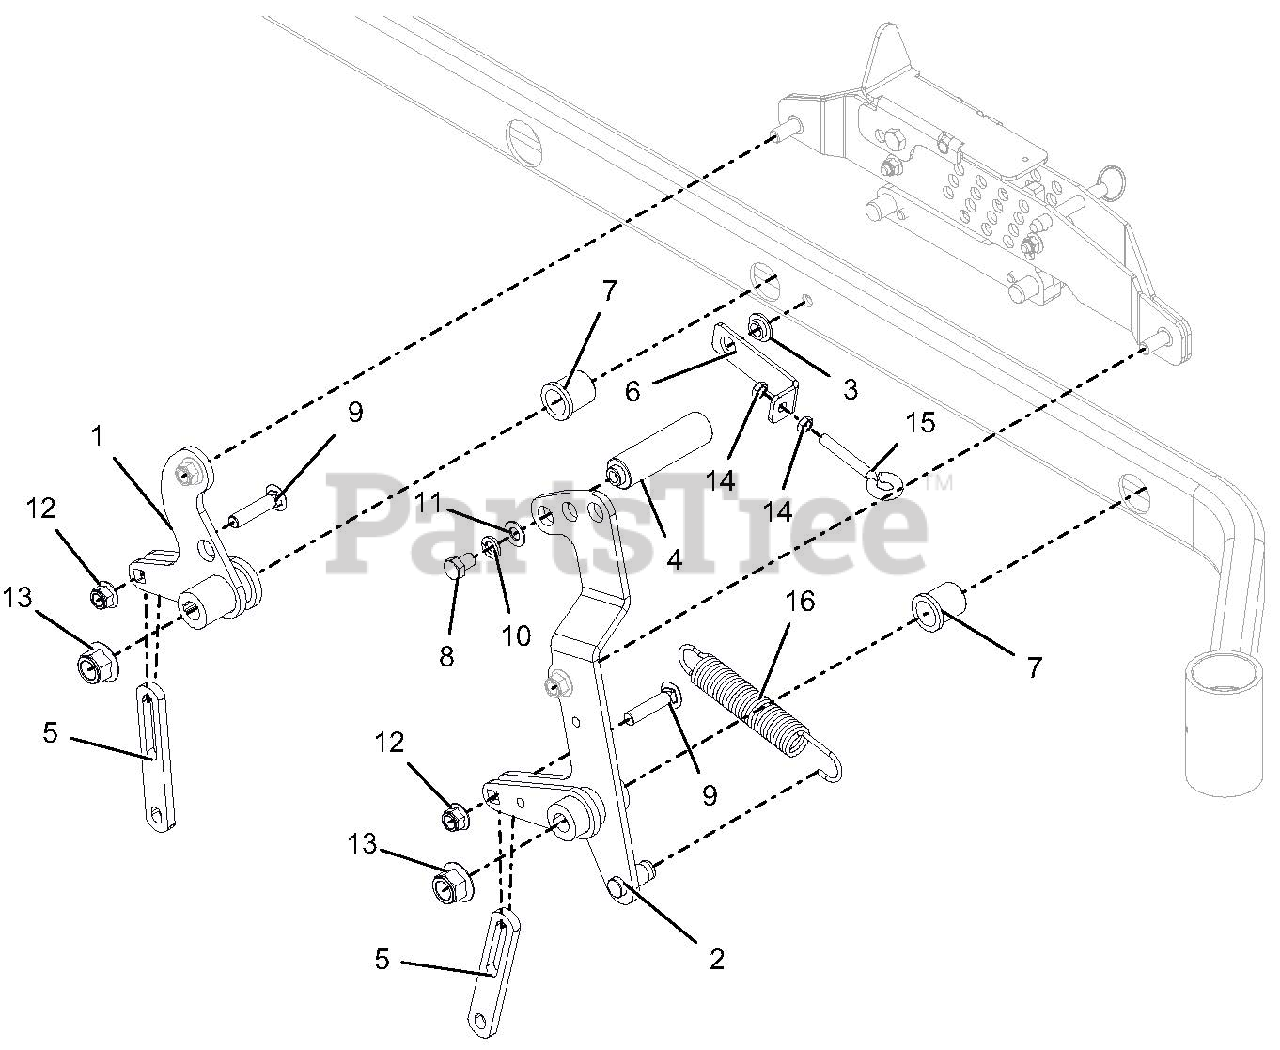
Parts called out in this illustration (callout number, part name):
1	WLDMT, REAR RH DECK LIFT ARM
2	WLDMT, FRONT RH DECK LIFT ARM
3	BSHG, FLANGE .515X.750X.31X1.12
4	PEDAL, LIFT
5	LINK, DECK LIFT - LONG
6	BRKT, SPRING ANCHOR
7	BSHG-FLG 1.00X1.25X1.5X1.5
8	BLT-HEX .50-13X.75 GR5 YWZC
9	BLT-RDHDSQNK .50-13X2.25 G5 Y
10	WSHR-LK .50X.125 REG YWZC
11	WSHR-FL-STL .505X1.00X.062 YWZC
12	NUT-LK-NYL-FLG .50-13 YWZC
13	NUT-LK-NYL-FLG .75-10 YWZC
14	NUT, JAM .375-16 YWZC
15	BOLT, EYE .375-16
16	SPRG, TENSION .162 X 1.250 X 8.250
